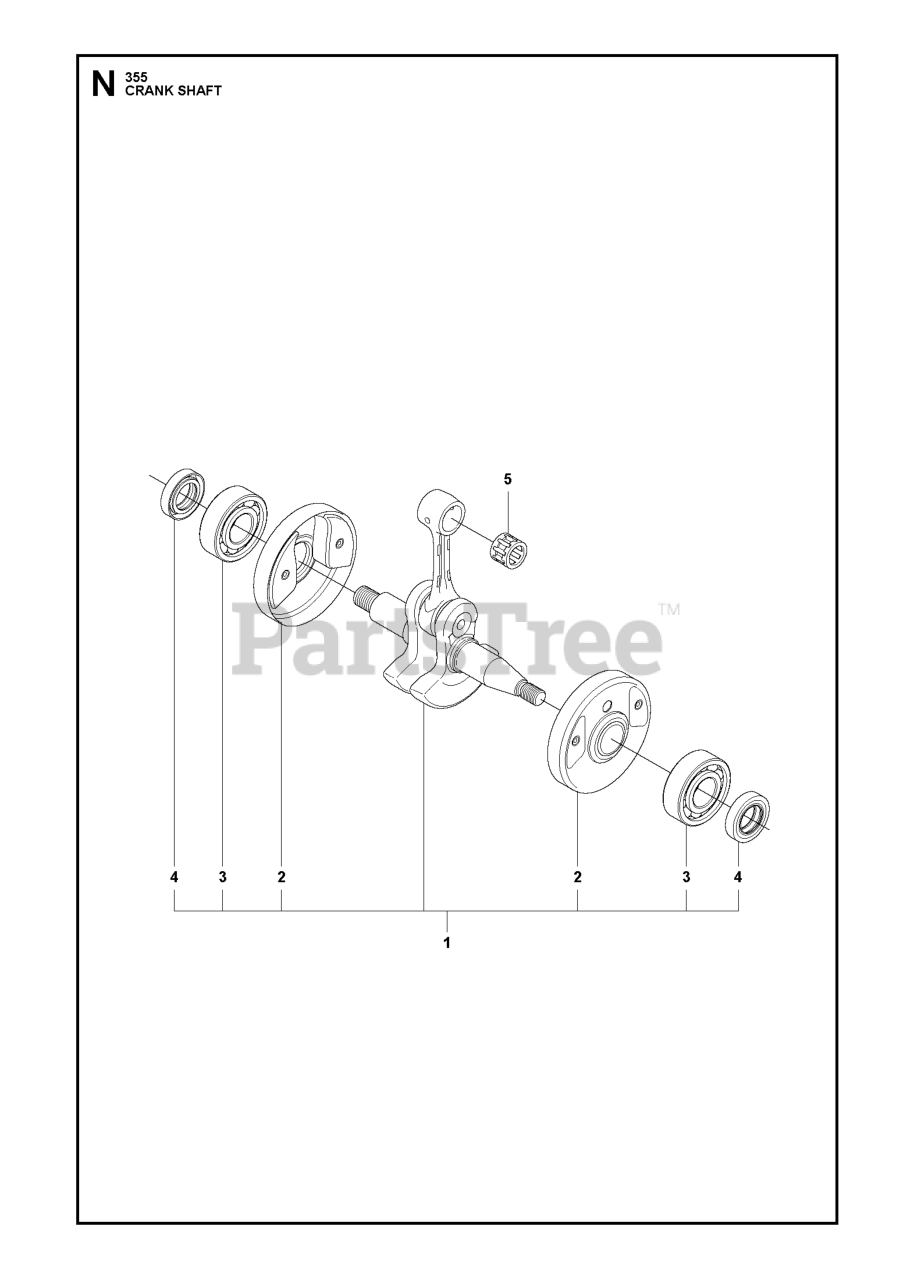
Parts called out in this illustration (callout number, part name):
1	CRANKSHAFT
3	BALL BEARING
4	SEALING RING
5	SUPPORT BUSHING
